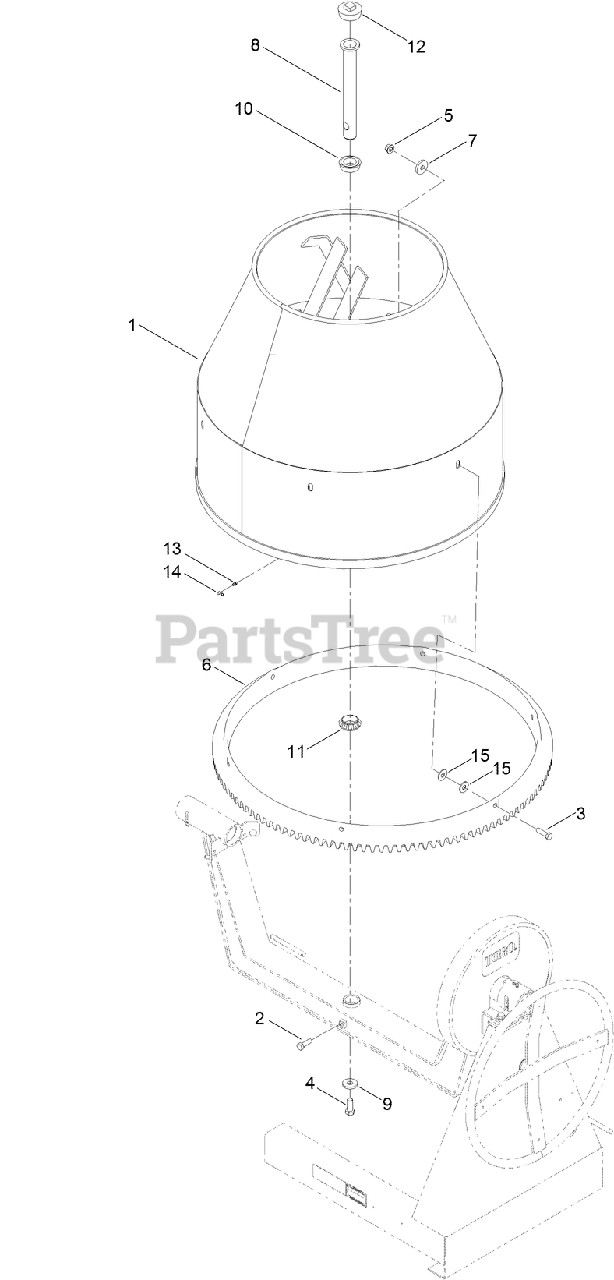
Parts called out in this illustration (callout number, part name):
2	SCREW-HH
3	SCREW-HH
4	SCREW-HH
5	NUT-LOCK
6	GEAR-RING
7	WASHER-FLAT
8	SPINDLE
9	WASHER-FLAT
10	BEARING
11	BEARING-ROLLER
13	FITTING
14	CAP-PLUG
15	WASHER-FLAT
